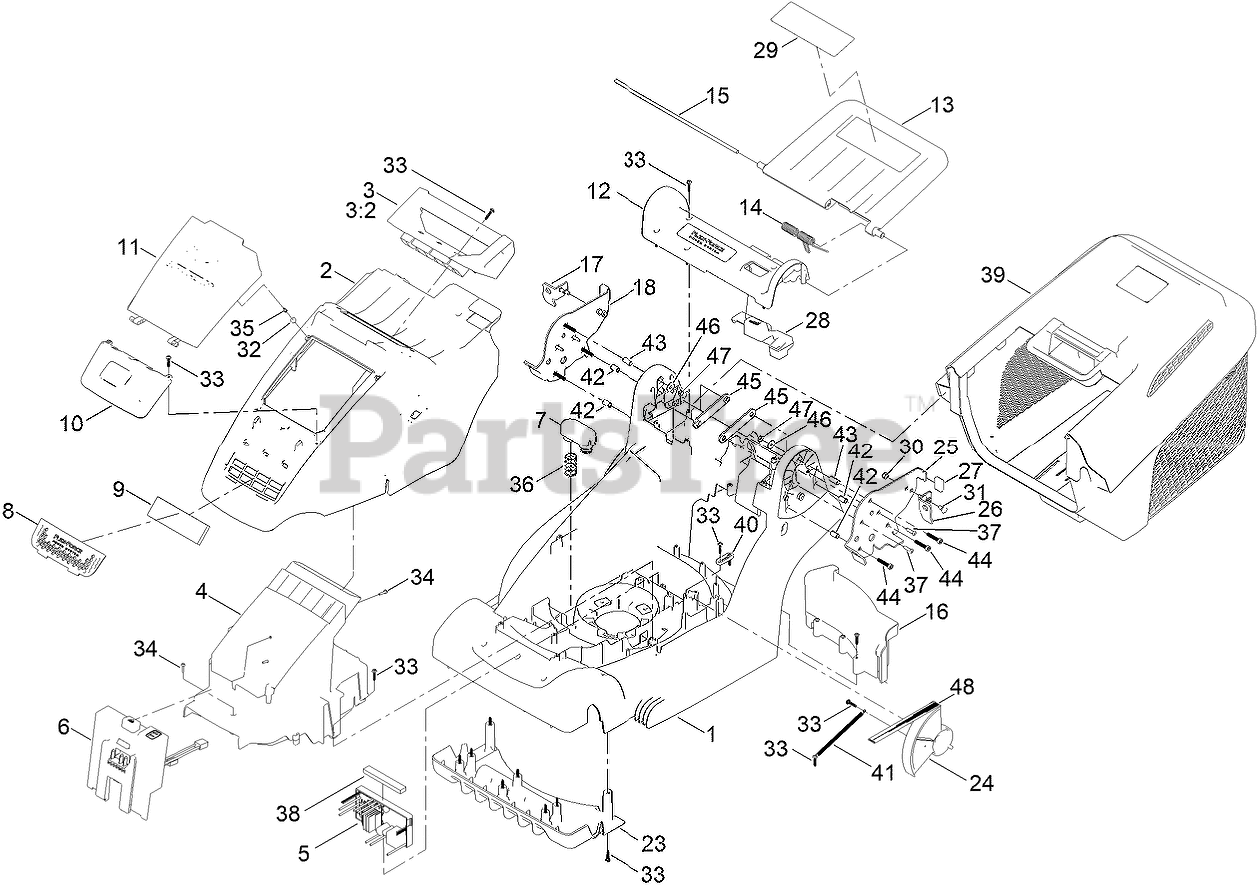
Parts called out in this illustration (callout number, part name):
2	TOP COVER
3	CARRY HANDLE ASM
3:2	ARTWORK - 43CM
4	BATTERY HOLDER
5	DRIVER-MOTOR, PUSH
6	BATTERY INTERFACE ASSEMBLY
7	BATTERY SPRING COVER
8	AIR INLET GRILL-TORO
9	Cover, Exhaust-Right
10	BATTERY DOOR LOWER, PRINTED
11	BATTERY DOOR, PRINTED
12	HOC COVER
13	REAR DEFLECTOR
14	SPRING, REAR DEFLECTOR
15	ROD, REAR FLAP
16	GRASS SHIELD (43)
17	BRACKET, V-STOW, RIGHT
18	MOUNT PLATE, HANDLEBAR, RIGHT
23	FRONT FINS
24	HOC DIAL
25	MOUNT PLATE, HANDLEBAR, LEFT
26	BRACKET, V-STOW, LEFT
27	RUBBER FOOT-V-STOW
28	HOC BUTTON
29	DECAL SAFETY 60V
30	NUT, NYLOC, M6X1
31	BOLT, CARRIAGE, M6X1
32	MAGNET
35	PT SCREW 3MM X 10MM CSK
36	SPRING, BATTERY EJECT
37	SCREW-TORX
38	FILTER, AIR-CONTROL BOARD
39	GRASS BOX ASM
41	SPRING
45	BRACE-BAR
46	WASHER
48	DECAL - HOC (TORO 43CM)
